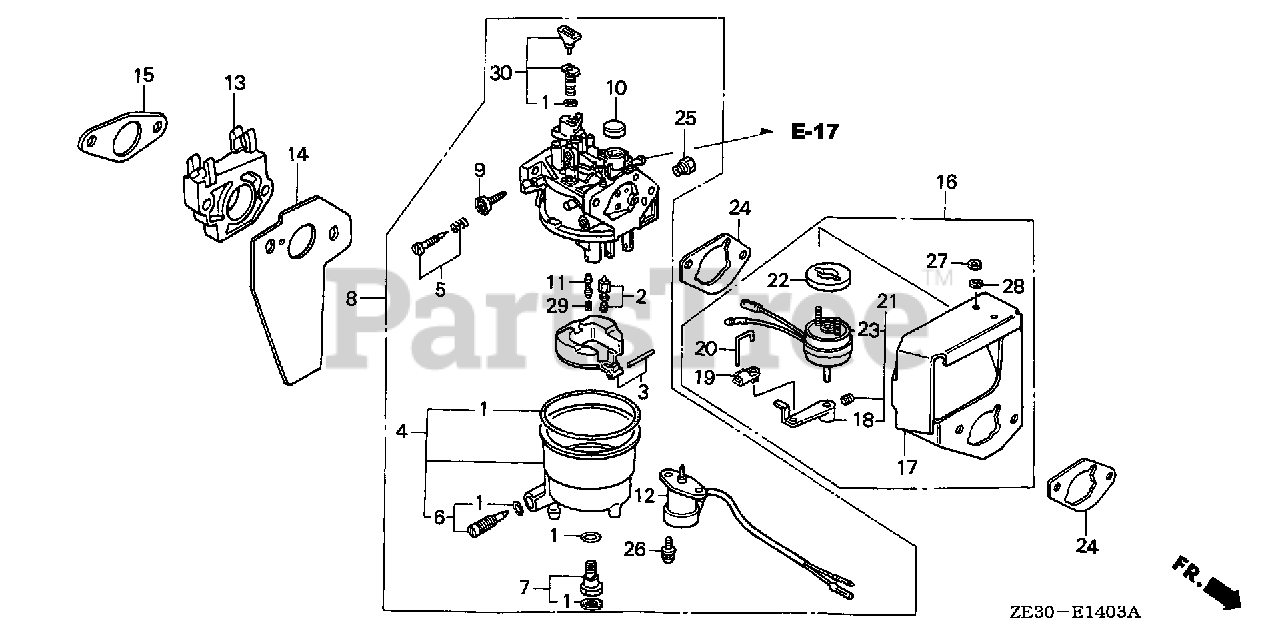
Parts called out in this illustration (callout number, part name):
1	GASKET SET
2	VALVE SET, FLOAT
4	CHAMBER SET, FLOAT
5	SCREW SET, PILOT
6	SCREW SET, DRAIN
8	CARBURETOR ASSY. (BE38B E) (NOT AVAILABLE)
9	SCREW, THROTTLE STOP
10	CAP, CHOKE DUST
11	NOZZLE, MAIN
12	VALVE ASSY., SOLENOID (NOT AVAILABLE)
13	INSULATOR, CARBURETOR
14	GASKET, CARBURETOR
15	GASKET, INSULATOR
16	STAY ASSY., SOLENOID
17	STAY, CHOKE SOLENOID
18	LEVER, CHOKE SOLENOID
19	JOINT, ROD
20	ROD, CHOKE SOLENOID
21	SOLENOID ASSY., CHOKE
22	SPACER, CHOKE SOLENOID
23	SOLENOID, ROTARY CHOKE
24	GASKET, AIR CLEANER
25	NUT, JOINT
26	SCREW-WASHER (6X12)
27	NUT, HEX. (3MM)
28	WASHER, SPRING (3MM)
29	JET, MAIN (#90)
29	JET, MAIN (#92)
29	JET, MAIN (#95)
30	JET SET, PILOT (#35)
